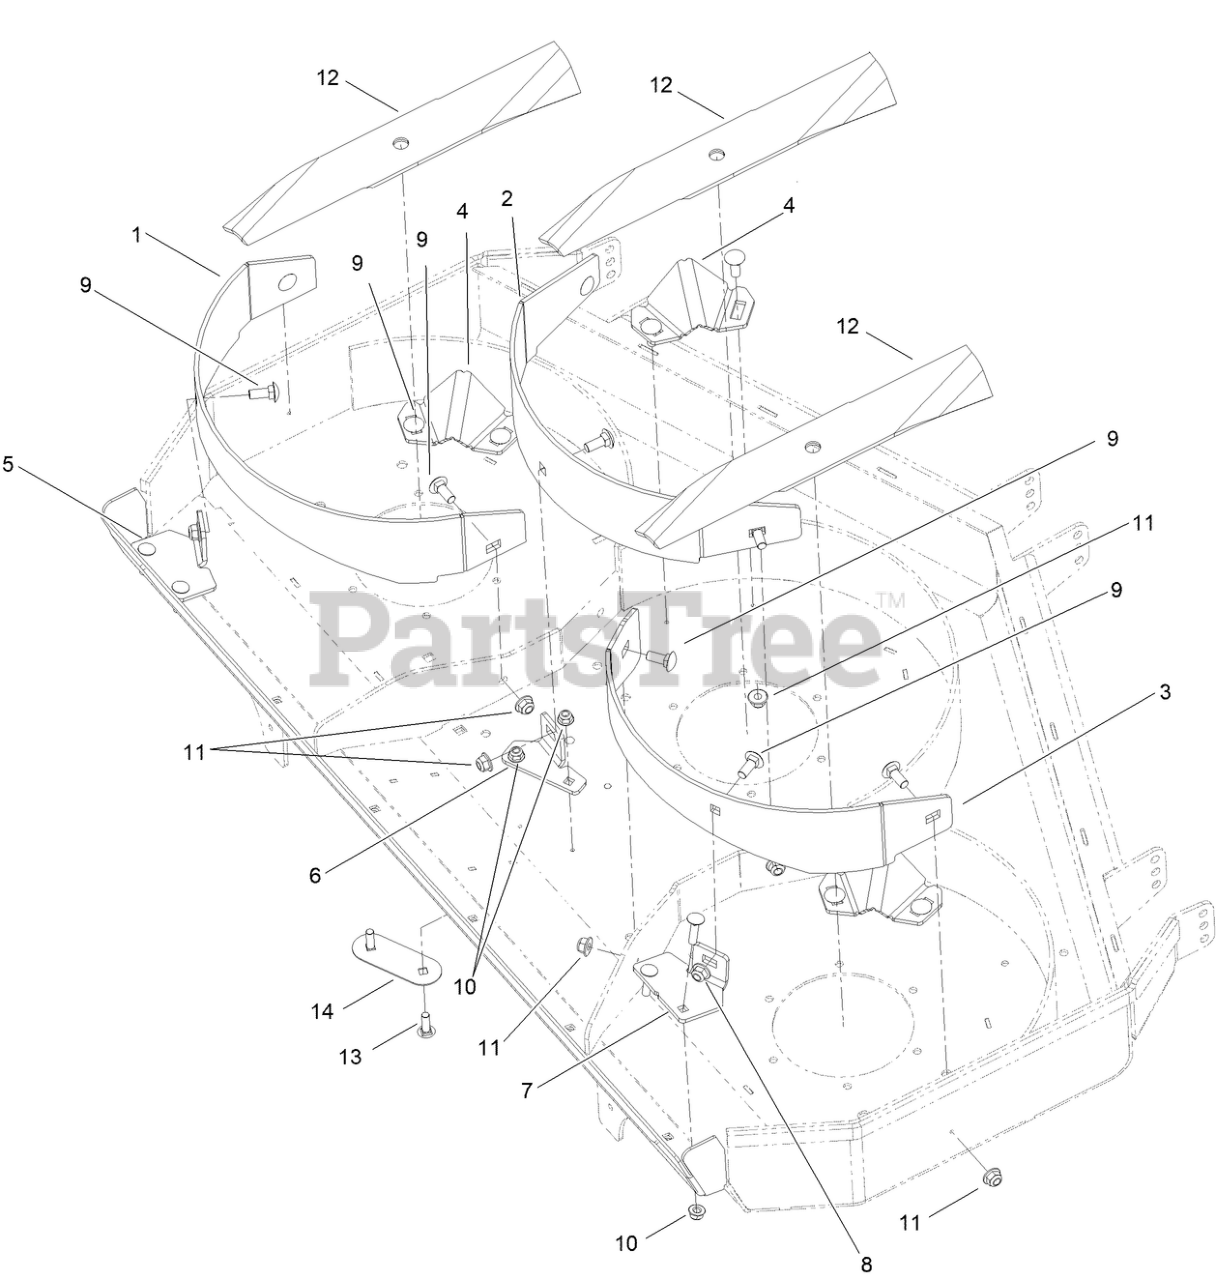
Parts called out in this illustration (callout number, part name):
1	BAFFLE- MULCHING RH, 48 (RD)
2	BAFFLE- MULCHING CTR, 48 (RD)
3	BAFFLE- MULCHING LH, 48 (RD)
5	SUPPORT, RH BAFFLE (RD)
6	SUPPORT, CTR BAFFLE (RD)
7	SUPPORT, LH BAFFLE (RD)
8	SCREW-CARR
9	BOLT-CARR
10	NUT-HF, NI
11	NUT-HF, NI
12	BLADE-ROTARY, RECYCLING 16.5IN
99	NUT-HF, NI
99	SCREW-HHF
